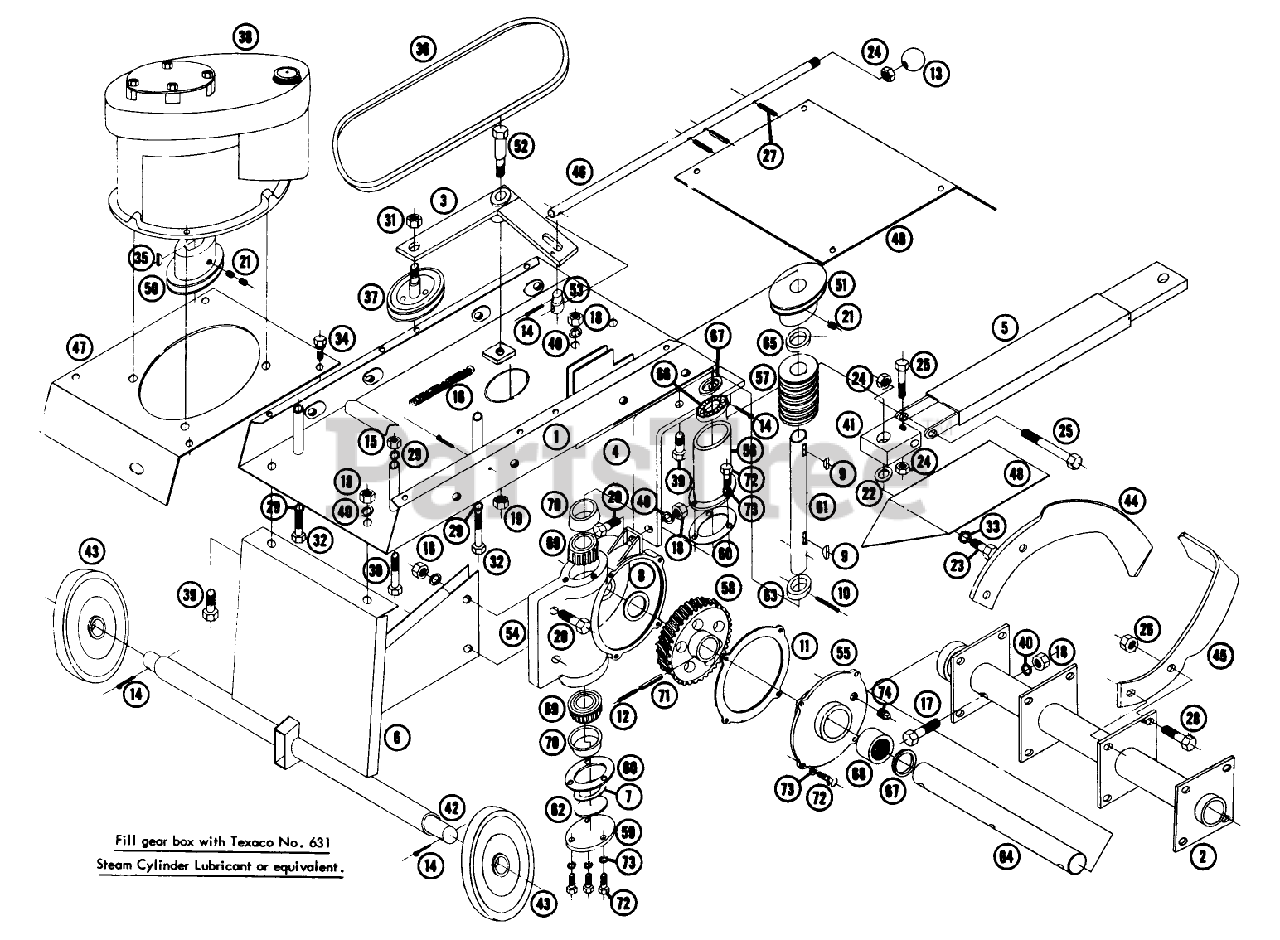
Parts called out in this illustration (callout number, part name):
1	Deck W/A
2	Tine Tube W/A
3	Clutch Arm W/A
4	Mounting Bar W/A
5	Hitch Bar W/A
6	Pivot Tube W/A
7	Shim
8	Shim
10	Roll Pin
11	Gasket
12	RoIl Pin
14	Cotter Key
15	Hex Nut
17	Hex Hd. Cap Screw 3/8-16 x 1 3/4
18	Lock Nut 3/8-16
19	Hex Nut-Self Locking 3/8-16
20	Hex Head Cap
21	Snap Ring
22	Washer 5/8 I.D.
23	Hex Head Cap
24	31300 '65-67&UP 20
25	Cap Screw, 3/8 x 2 1/2
26	Hex Nut 7/16-14 Lock Nut
28	H.H.C.S. 7/16-14 x 1 1/4 Lg.
29	Lock Washer 5/16
30	H.H.C.S. 5/16-18 x 3 3/4
32	H.H.C.S. 5/16-18 x 3
33	Shakeproof Washer 3/8
35	Woooruff Key #6
38	Engine
39	Hex Head Cap
40	Lockwasher
41	Swivel Block
42	Axle
44	Tine R.H.
45	Tine L.H.
46	Oil Seal
47	Plate-Top Rear
48	Cover-Tine
49	Top Plate
50	Engine Pulley
51	Pulley
52	Bolt-Shoulder
53	Stud
54	Case-Tiller (Cast Iron)
55	Cover
56	Support
57	Worm Gear
58	Worm
59	Plate
60	Gasket
61	Worm Shaft
62	Disc
63	Spacer
64	Shaft-Tine
69	Cone-Bearing
71	Roll Pin 5/16 x 1 3/4
72	H.H.C.S. 1/4-20 x 5/8
73	Lockwasher 1/4
